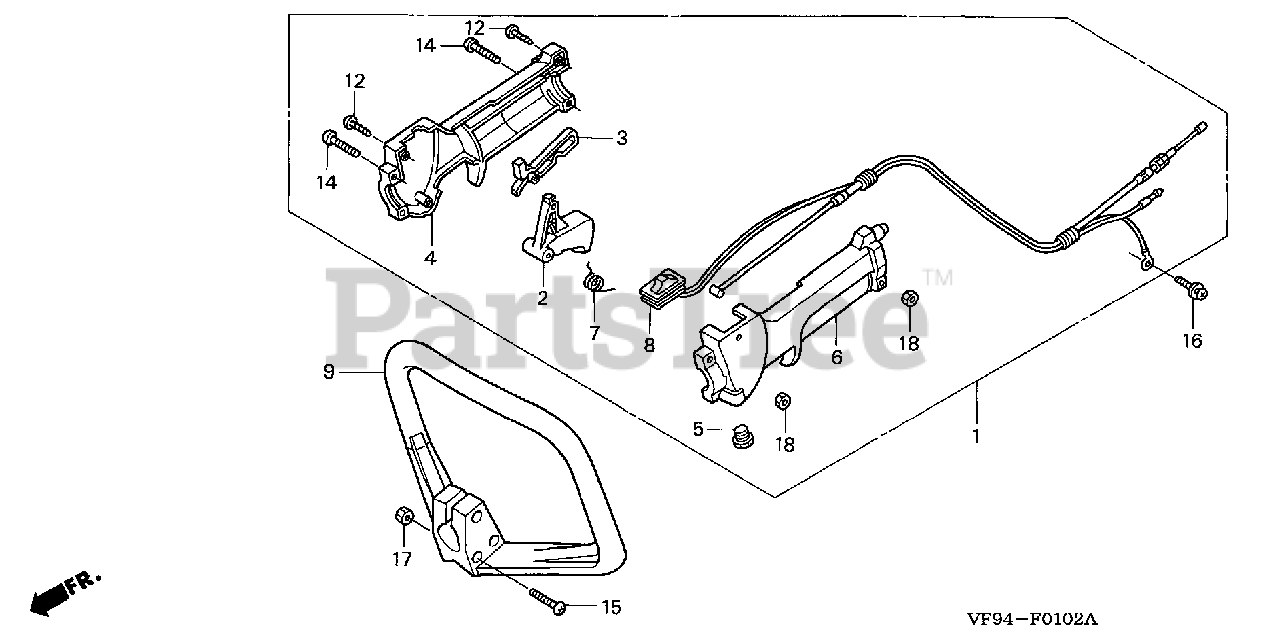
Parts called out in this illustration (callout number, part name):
1	LEVER ASSY., THROTTLE (L24)
2	LEVER, THROTTLE
3	LEVER, THROTTLE LOCK
4	GRIP, R. THROTTLE LEVER
5	CAP, THROTTLE LEVER
6	GRIP, L. THROTTLE LEVER
7	SPRING, THROTTLE LEVER
8	WIRE HARNESS ASSY.
9	HANDLE, LOOP
12	SCREW, TAPPING (4X20)
14	SCREW, PAN (5X20)
15	SCREW, PAN (5X28)
16	SCREW-WASHER (5X12)
17	NUT, HEX. (5MM)
18	NUT, HEX. (5MM)
